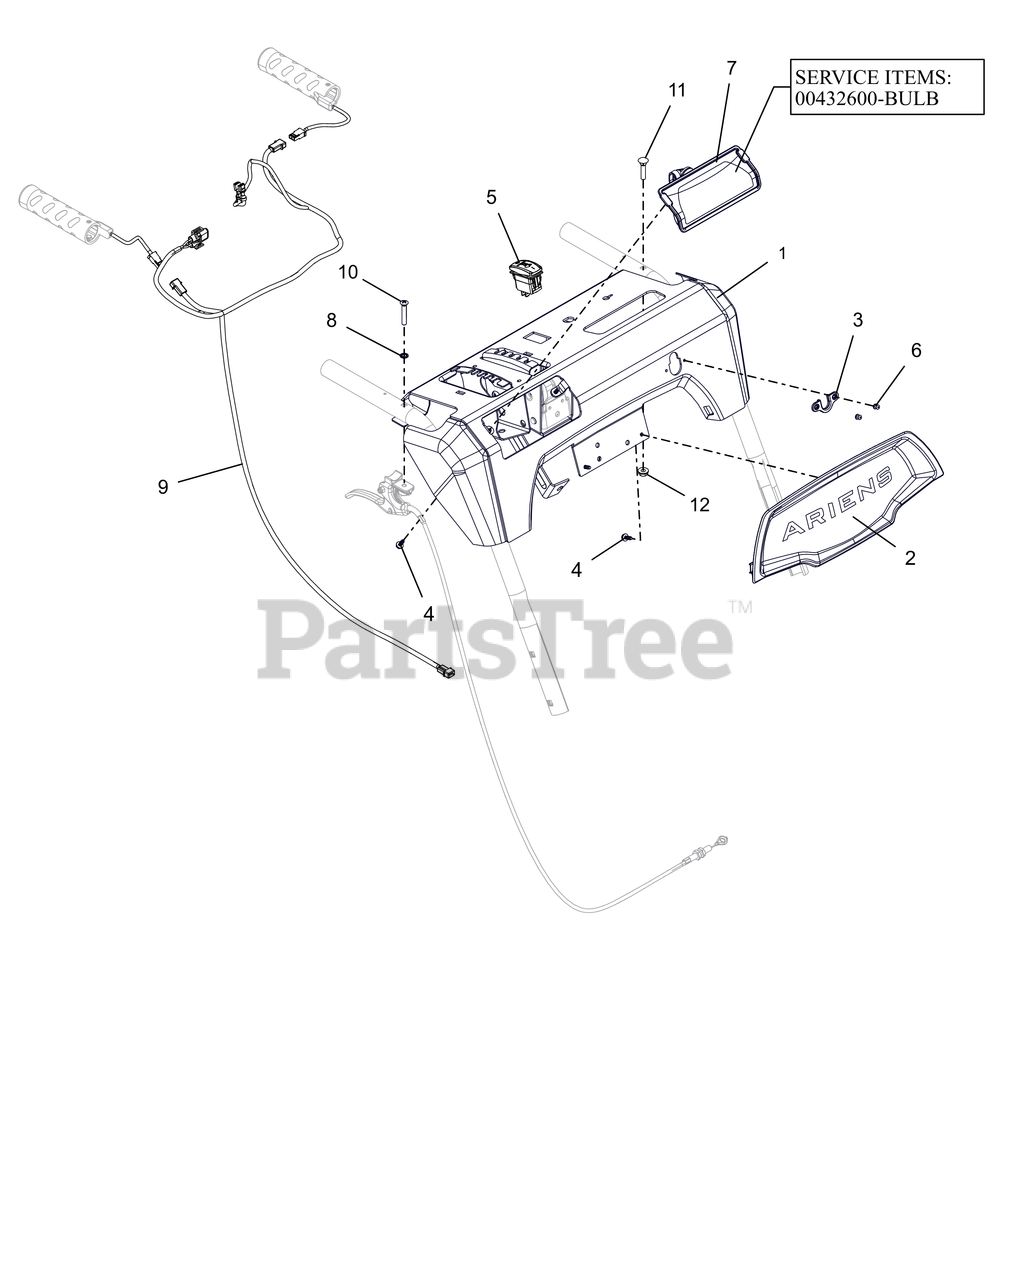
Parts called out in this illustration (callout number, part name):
1	CONTROL PANEL W/DECAL FRIC-TRK
2	BEZEL, DASH - ARIENS LG DASH
3	GROMMET, CABLE, QUICK TURN 2
4	SCR, PLASTIC #10X.50
5	SWITCH,ROCKER SPST-ON/OFF
6	RVT-POP #43 .125X.313 STL ZINC
7	HEADLIGHT ASY, HALO 20W 2SHOT
7	BULB, LIGHT-HALOGEN 20W
8	WSHR-LK-INT .250 TH TYA
9	HARNESS, LIGHT & WARMER
10	SCR,OVAL .25-20X1.50 ZCC
11	BLT-RDHDXLSQNK.25-20X1.25 G5ZC
12	NUT-LK-CTR-FLG .25-20 ZC120
